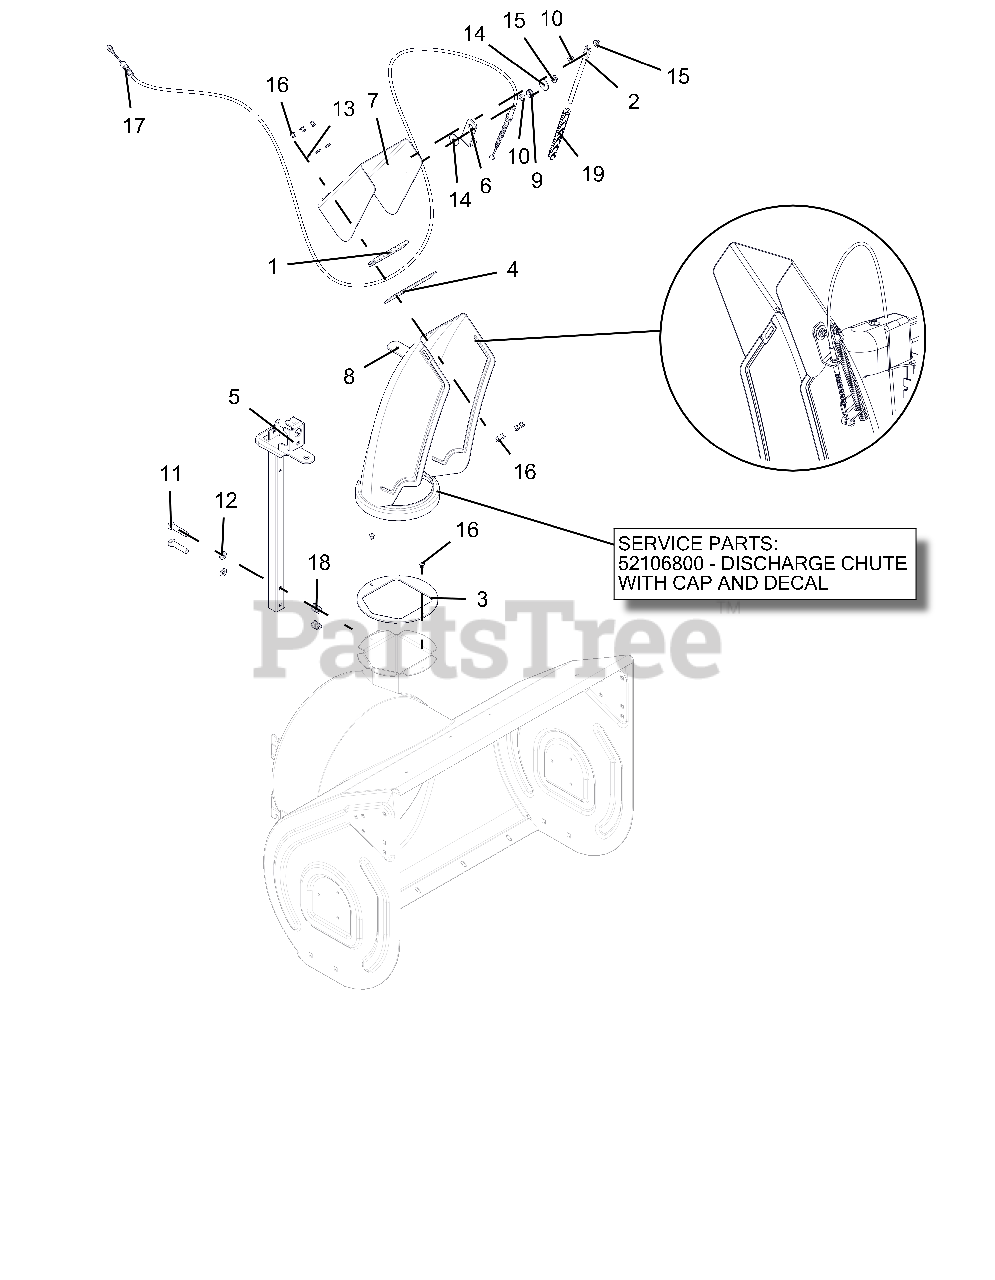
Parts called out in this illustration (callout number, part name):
2	ROD, DEFLECTOR CAP
3	BAFFLE, DISCHARGE NECK
4	CAP SEAL 5.50
5	PEDESTAL, CHUTE - QUICK STICK
6	BRACKET, CABLE ANCHOR
7	CAP,LARGE,REMOTE
8	CHUTE,DISCHARGE,NOTCHED,QT
8	KIT, DISCHARGE CHUTE W/DEF QT2
9	BUSHING, POLYLINER-.50 SNAPIN
10	BSHG-SLV .265X.500X.219
11	@BLT-HEX .38-16X1.75 GR5 YWZC
12	@WSHR-LK .38X.094 REG YWZC
13	WSHR-FL-STL .196X.500X.06 YZ
14	WSHR-FL-STL .281X1.000X.063
15	@NUT-LK-CTR-FLG .25-20 YWZC
16	RVT-POP .187 YZ
17	CABLE, DEFLECTOR - DELUXE
18	NUT, THREADED INSERT .38-16
19	SG-COMP .08X.40X6.50 14#/IN
